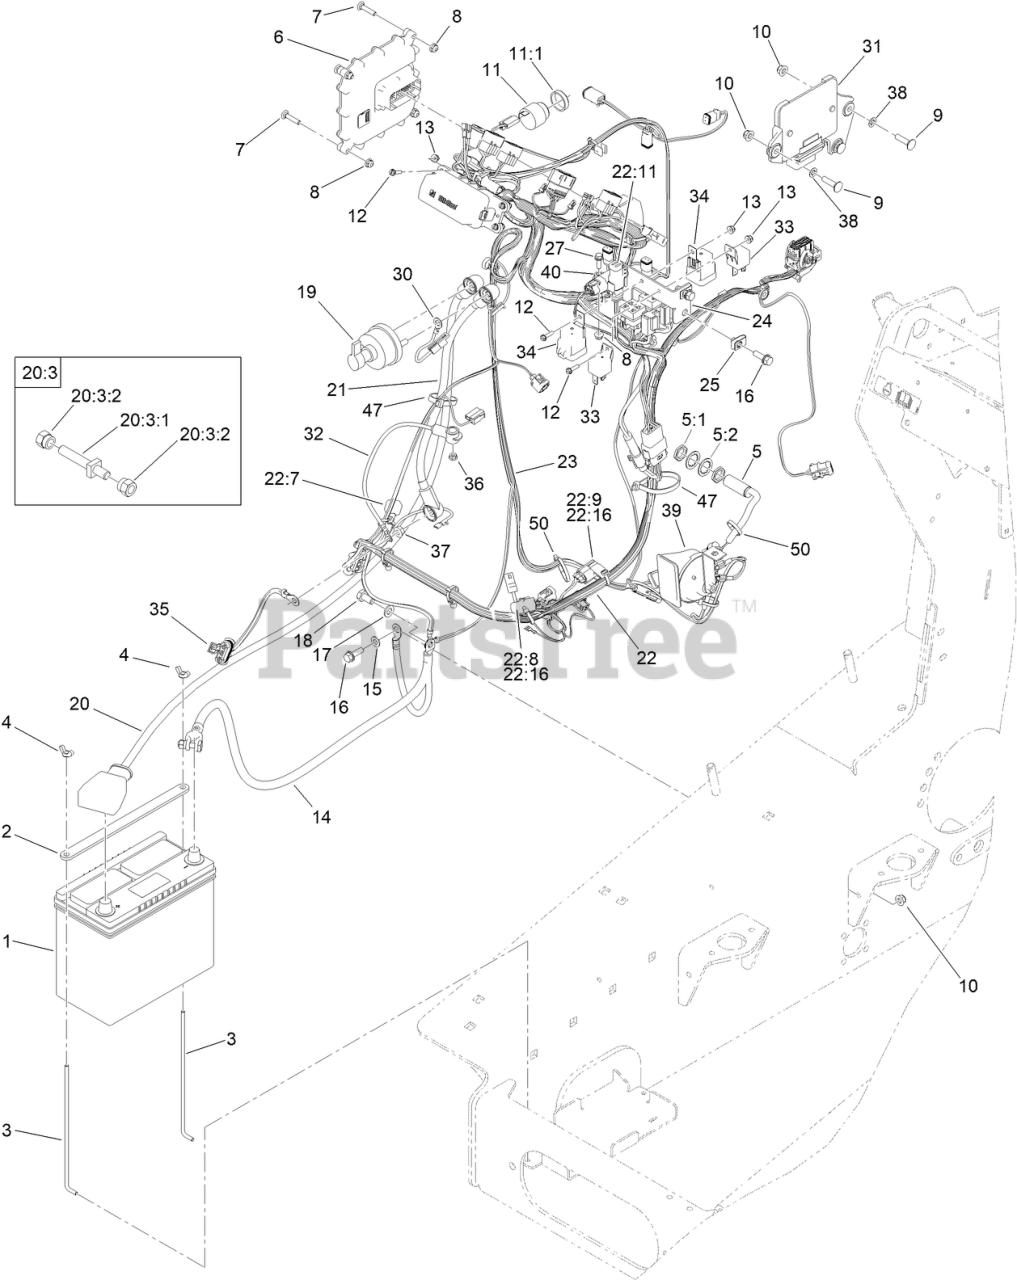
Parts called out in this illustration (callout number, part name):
1	BATTERY-GROUP 51
2	PLATE-HOLD DOWN, BATTERY
3	ROD-HOLD DOWN, BATTERY
4	NUT-WING
5	PROXIMITY SWITCH ASM
5:1	NUT-HEX
5:2	WASHER-LOCK, INTERNAL TOOTH
6	CONTROLLER
7	SCREW-CARR
8	NUT-HF
9	SCREW-CARR
10	NUT-HF, NI
11	AUDIO ALARM ASM
11:1	NUT-PLASTIC, KNURLED
12	SCREW-HWH
13	NUT-HF
14	CABLE-BATTERY, NEGATIVE
15	WASHER-PLAIN
16	SCREW-HHF
17	WASHER-FLAT
18	SCREW-HH
19	SWITCH-DISCONNECT, MASTER
20	CABLE-BATTERY, RD ASM
20:3	BOLT ASM
20:3:1	BOLT-CLAMP, BATTERY
20:3:2	NUT-CLAMP, BATTERY
21	CABLE-BATTERY, RD ASM
22	HARNESS-WIRE, ENGINE
22:8	FUSE-MINI BLADE, 2 AMP
22:9	FUSE-MINI BLADE, 10 AMP
22:11	CONNECTOR (6M)
22:16	COVER-FUSE, SINGLE
23	HARNESS-WIRE, MAIN
24	BRACKET-RELAY
25	NUT-CLIP, U
27	SCREW-HHF
30	HARNESS-WIRE, FUSIBLE LINK
31	CONTROLLER-ENGINE
32	HARNESS-WIRE
33	RELAY
34	RELAY-MINI
35	HARNESS-WIRE, FUSIBLE LINK
36	NUT-HF
37	NUT-HF
38	RING-RETAINING, BOLT
39	Horn And Bracket Assembly (Inc. Ref.# 44 45)
40	SENSOR-ATM
47	TIE-CABLE
50	TIE-CABLE
